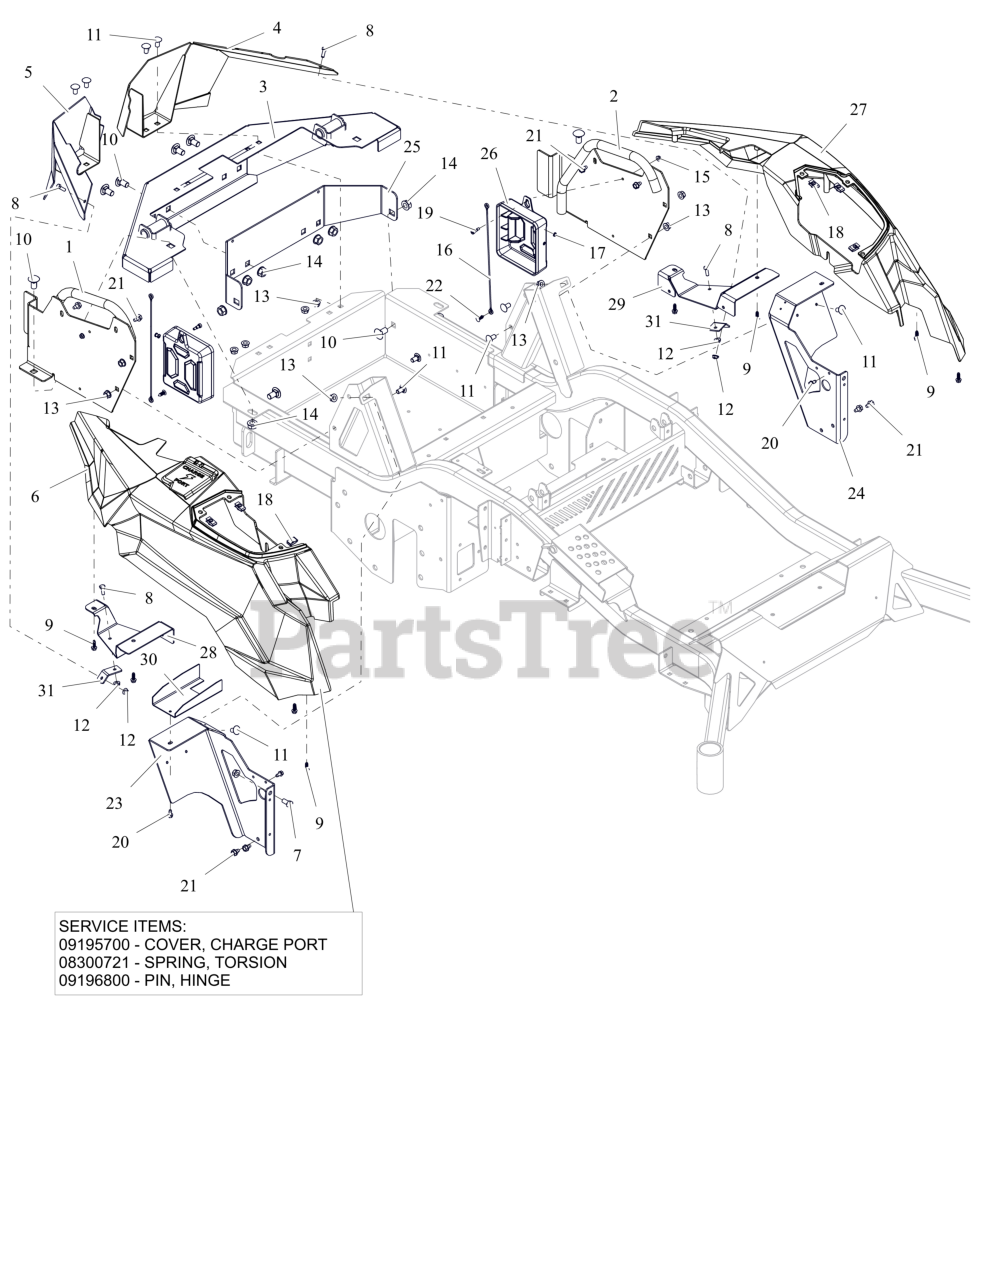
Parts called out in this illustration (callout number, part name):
1	WLDMT, REAR FENDER MOUNT-RH (ORANGE)
2	WLDMT, REAR FENDER MOUNT-LH (ORANGE)
3	WLDMT, BUMPER ZENITH E (ORANGE)
4	WLDMT, REAR WRAP-LH (BLACK)
5	WLDMT, REAR WRAP-RH (BLACK)
6	ASM, FENDER RH PRO-TURN EV
6	COVER, CHARGE PORT
6	SPRING, TORSION
6	PIN, HINGE
7	BLT,HEX .38-16X.75 G5 ZCC
8	BLT, HEX .25-20X.75 G5 ZCC
9	SCR, PLASTITE .25-10X.75 ZCC
10	BLT, RHSN .50-13X1.00 G5 ZCC
11	BTL,RHSSN .375-16 X 0.75 G5 FPB
12	NUT-LK-CTR-FLG .25-20 ZC120
13	NUT-LK-CTR-FLG .375-16 GF ZCC
14	NUT-LK-CTR-FLG .500-13 GG ZCC
15	NUT, FLG-TOP LK #10-24 GF ZCC
16	CABLE, 12.0 LANYARD, NYLON
17	POST, & SCREW, PUSH LOCK .25 X .25
18	NUT-RTNR .25-20X.56
19	BLT-SHLDR .25X.375
20	SCR-TAP .25-20X.50 HWH ZCC
21	SCR,TAP .312-18X.50 HWH TR ZCC
22	RIVET, .25 NYLON PANEL
23	MOUNT, FRONT FENDER-RH (ORANGE)
24	MOUNT, FRONT FENDER-LH (ORANGE)
25	SUPPORT, BUMPER (BLACK)
26	COVER, BATTERY BUSBAR TERMINAL
27	FENDER, LH PRO-TURN EV
28	SHIELD, FENDER MOUNT -RH (BLACK)
29	SHIELD, FENDER MOUNT-LH (BLACK)
30	SHIELD, DEBRIS -CHARGE PORT (BLACK)
31	STRAP, SUPPORT - REAR WRAP (BLACK)
